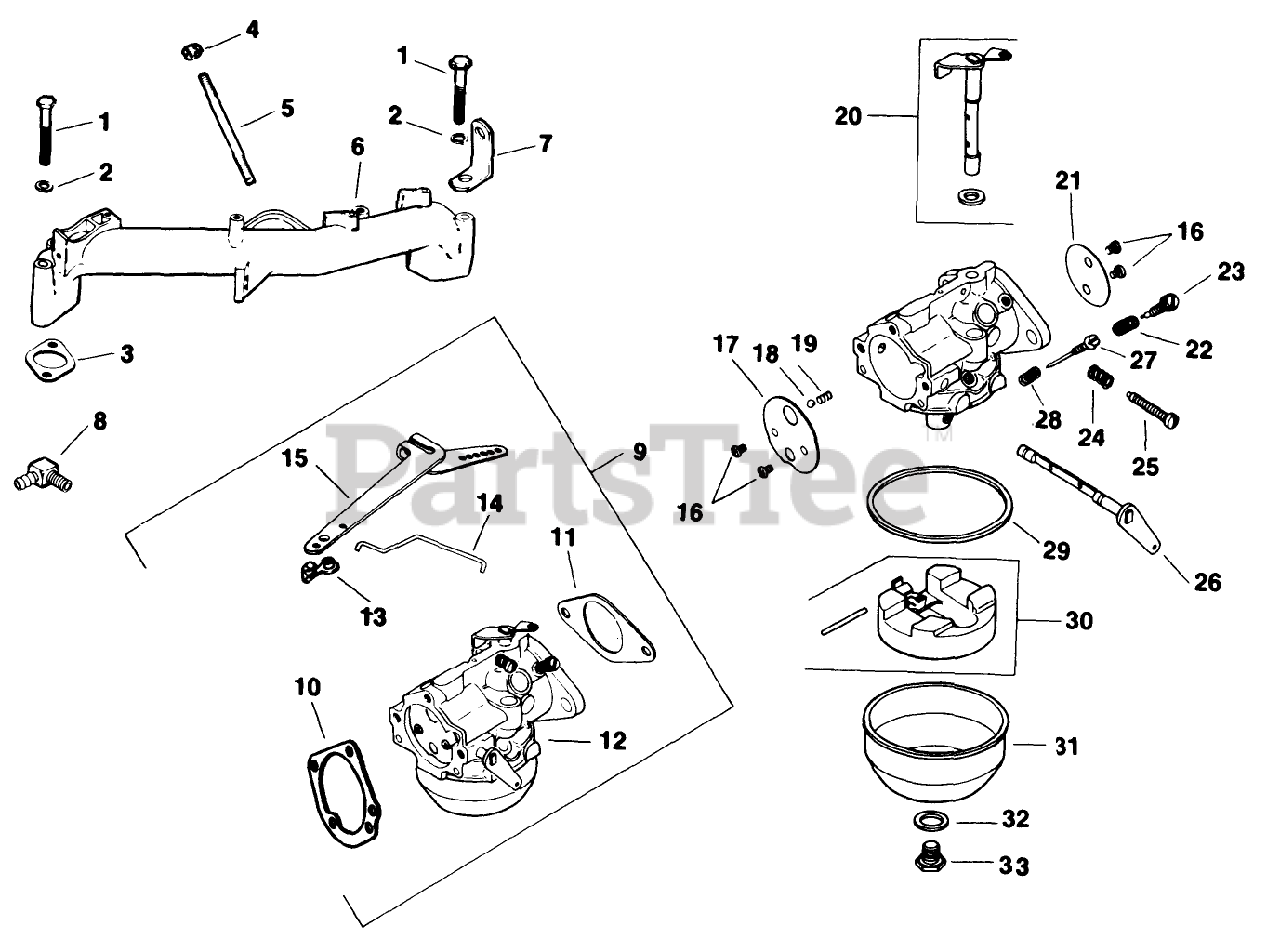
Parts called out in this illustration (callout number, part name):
1	Screw-H.C.
2	Washer
3	Gasket-Intake
4	Nut
5	Stud
6	Manifold-Intake
7	Strap-Lifting
8	Connector-90deg.
9	Kit-Carburetor w/Gasket (Incl. Ref. #10-33)
10	Gasket
11	Gasket
12	Carburetor
13	Bushing
14	Kit-Governor Linkage (Incl. Ref. #13)
15	Arm-Governor
16	Screw-Throttle Plate
17	Plate-Choke
18	Ball-Choke
19	Spring-Choke
20	Shaft-Throttle Lever & Sea
21	Plate-Throttle
23	Valve-Needle
26	Lever-Choke
27	Needle-Main Fuel
29	Bowl-Gasket
30	Kit-Float
32	Gasket-Bowl
33	Screw-Bowl
